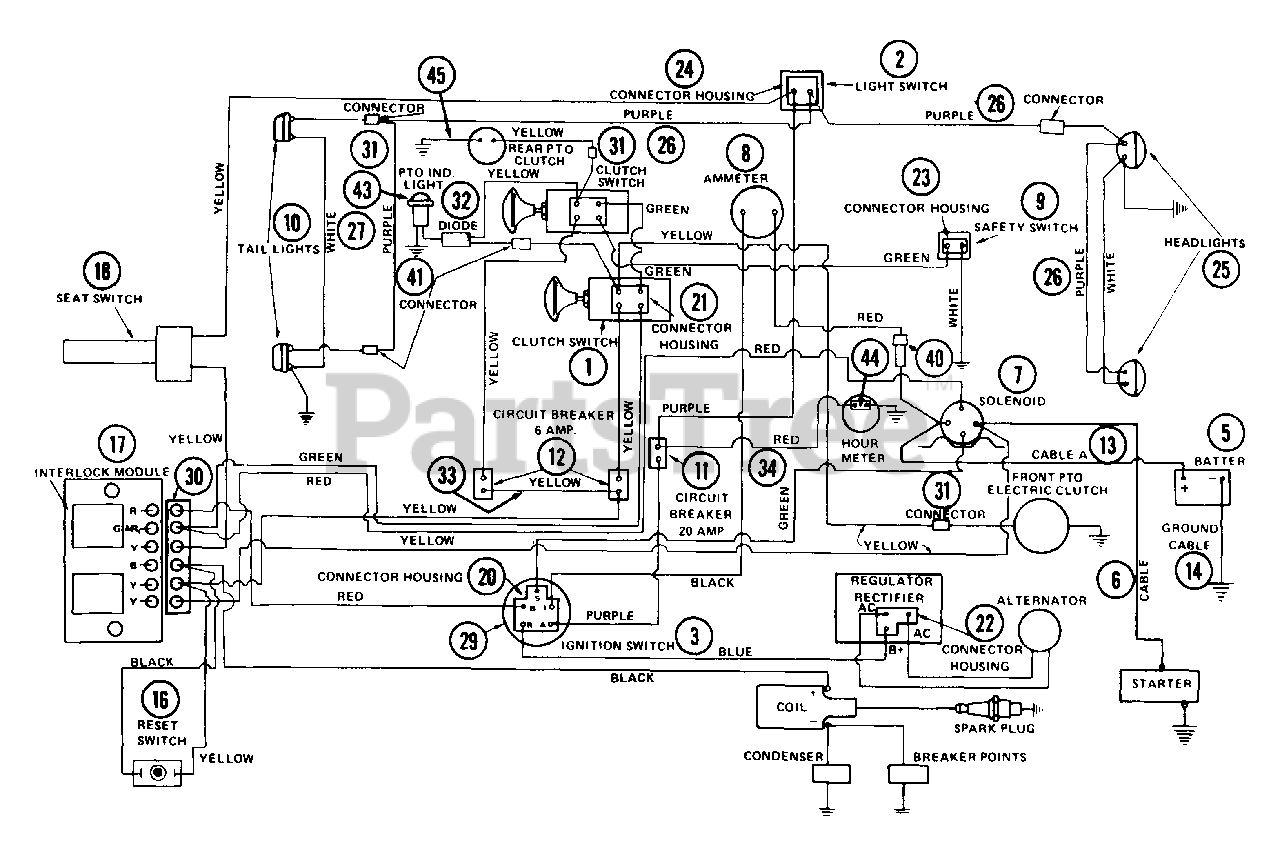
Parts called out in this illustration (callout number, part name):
1	CLUTCH SWITCH
2	LIGHT SWITCH
3	IGNITION SWITCH
5	BATTERY
6	GROUND CABLE .31X22.00X.31
7	SOLENOID
8	AMMETER
9	SAFETY SWITCH
10	TAIL LIGHT
11	CIRCUIT BREAKER
12	CIRCUIT BREAKER
14	GROUND CABLE
17	INTERLOCK MODULE
18	SWITCH SEAT
20	CONNECTOR HOUSING
21	CONNECTOR
22	CONNECTOR
23	CONNECTOR
24	CONNECTOR
25	HEAD LIGHT
26	HEAD LIGHT HARNESS
27	TAIL LIGHT HARNESS
29	DASH HARNESS
30	INTERLOCK MODULE HARNESS
31	WIRE CONNECTOR
32	WIRE ASSY
34	WIRING HARNESS
40	STD, 3A SAE FUSE
43	PTO INDICATOR LIGHT
43	LAMP
44	HOUR METER
45	R H INNER TINE SPOOL
